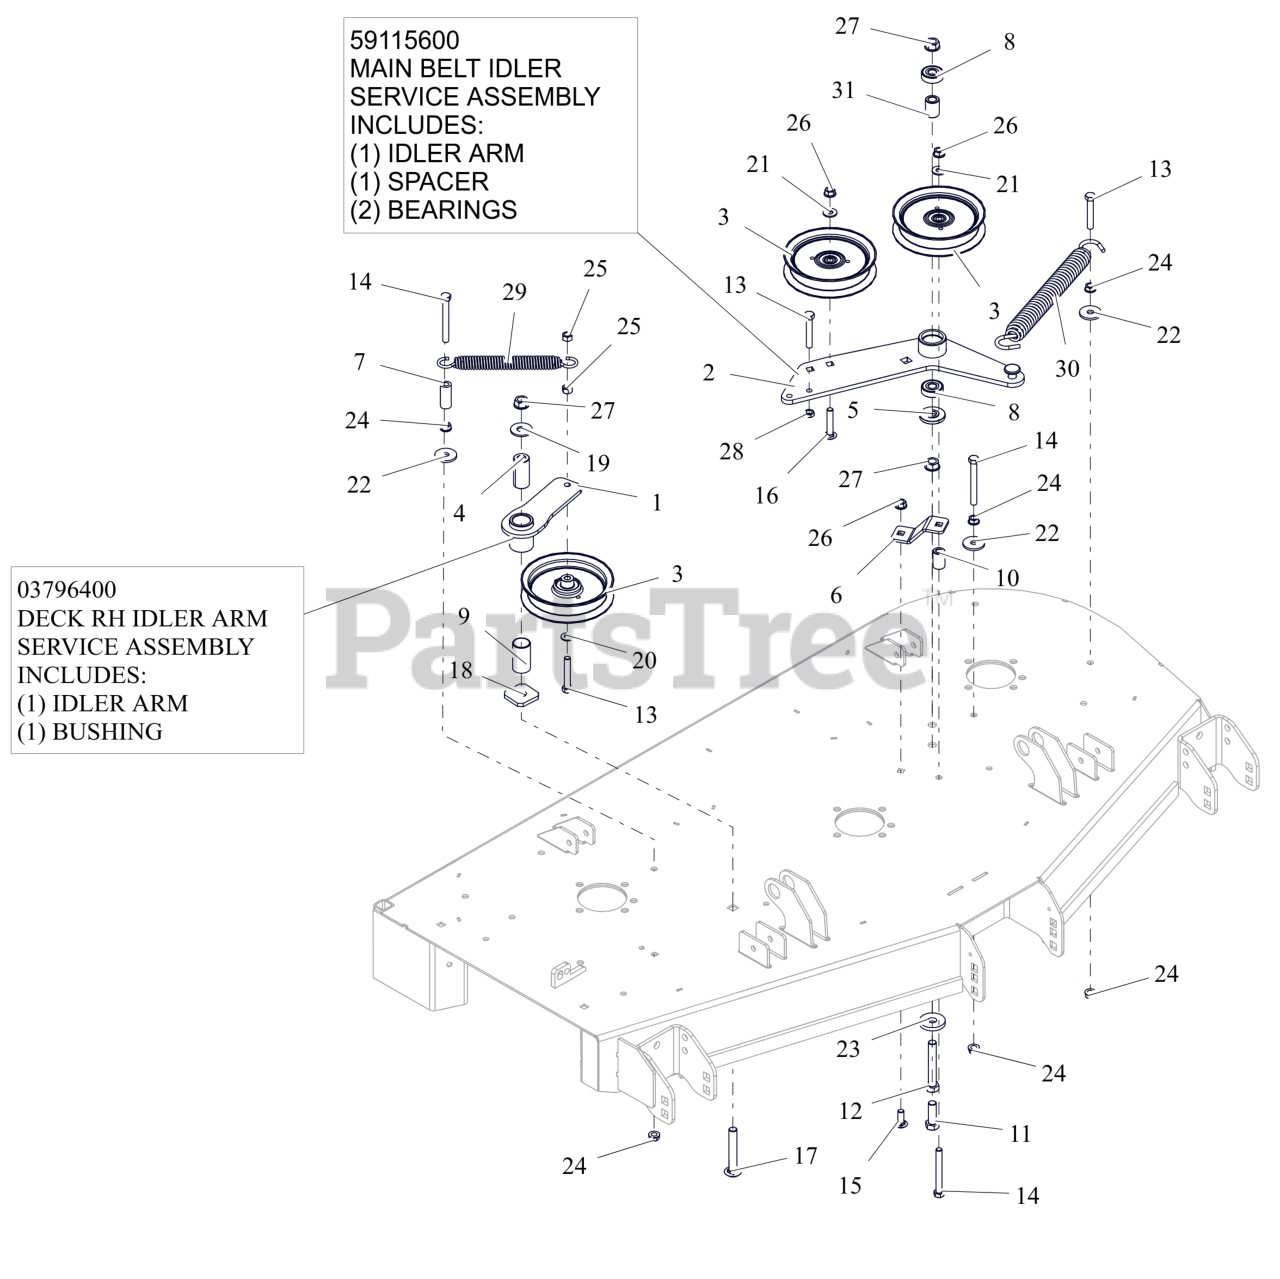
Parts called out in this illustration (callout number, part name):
1	WMT, IDLER ARM - BLACK
1	ASM, IDLER ARM (DECK)
2	WLDMT, DECK PTO IDLR ARM
2	ASSEMBLY, MAIN BELT IDLER
3	IDLER, FLAT 5.00"
4	BSHG, SPCR .502X.997X2.03 PM
5	SPACER, IDLER ARM
6	PTO FIXED IDLER MTG BRKT -RED
7	HOSE, .38 X 1.65
8	BRG-BALL .500X1.38X.437
9	BSHG, 1.00X1.125X1.937
10	BUSHING, SLV .380X.750X1.190
11	BLT,HEX .50-13X1.50 G5 ZCC
12	BLT,HEX .50-13X3.25 G5 ZCC
13	BLT,HEX .38-16X2.25 G5 ZCC
14	BLT, HEX .38-16X3.25 G5 ZCC
15	BLT,RHSSN .38-16X1.00 G5 ZCC
16	BLT,RHSSN.375-16X2.00 G5 ZCC
17	BTL,RHSSN .500-13 X 3.25 G5 ZCC
18	WSHR-FLT .640X1.75X.250
19	WSHR,FLT .563X1.375X.109 ZCC
20	WSHR,FLT .406X.812X.065 ZCC
21	WSHR,FLT .375X.875X.083 ZCC
22	WSHR,FLT .406X1.375X.135 ZCC
23	WSHR-FL-STL 0.557X1.625X0.25 ZCC
24	NUT, SPNLK-FLG .38-16 G5 ZCC
25	NUT-LK-CTR .38-16 ZC120
26	NUT-LK-CTR-FLG .375-16 GF ZCC
27	NUT-LK-CTR-FLG .500-13 GG ZCC
28	NUT-JAM .375-16 G2 ZCC
29	SPRING, EXTENSION
30	SPRING, EXTENSION
31	SPACER .510 X .75 X 1.1485
